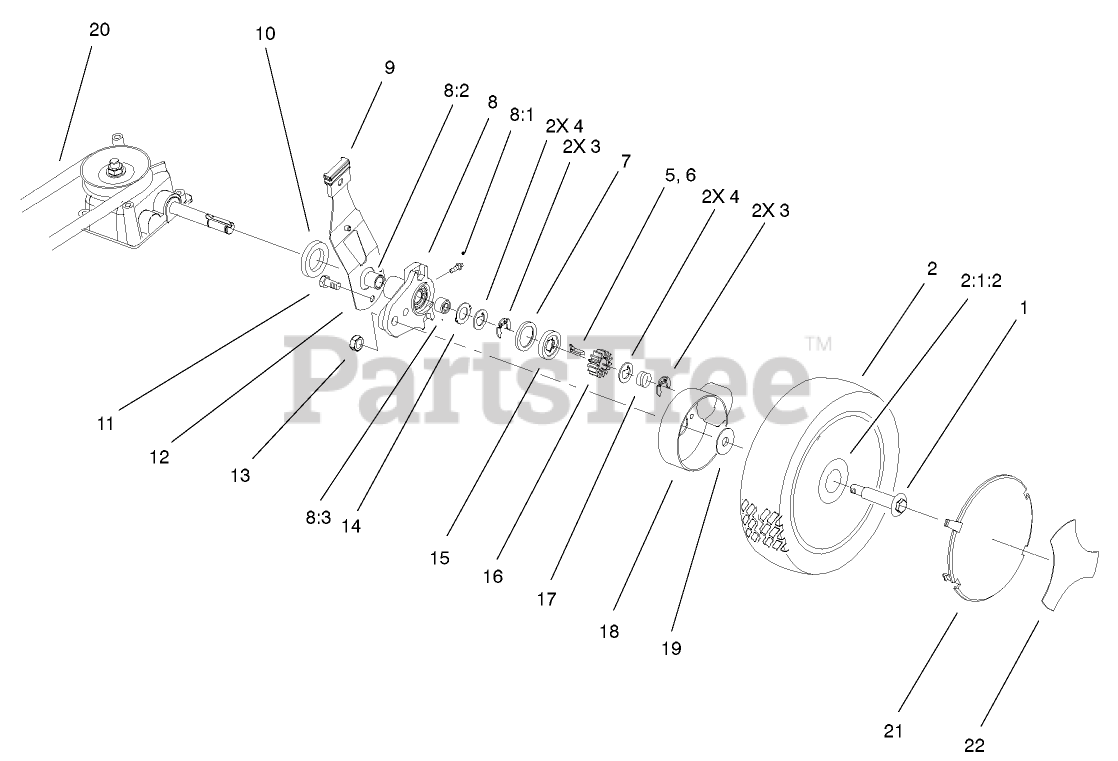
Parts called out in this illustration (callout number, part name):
1	BOLT-SHOULDER
2	WHEEL AND TIRE ASM
2:1:2	BUSHING
3	RING-RETAINING,CLIP
4	WASHER-THRUST, KEYED
5	KEY-ROCKING, RH
6	KEY-ROCKING, LH
7	RING-FRICTION
8	REAR HEIGHT ADJUSTMENT ARM ASM
8:1	FITTING-GREASE
8:2	BUSHING
8:3	BUSHING
9	KNOB-LEVER, HEIGHT ADJUSTMENT
10	SPACER-SHAFT, AXLE
11	SCREW-HWH
12	REAR SPRING ARM ASM
13	LOCKNUT
14	WASHER-ARM, PIVOT
15	WASHER-CLUTCH
16	GEAR-PINION
17	SPRING-COMPRESSION
18	COVER-WHEEL
19	WASHER-STEPPED
20	V-BELT
21	COVER-WHEEL, SMART
22	LABEL-WHEEL, SMART
